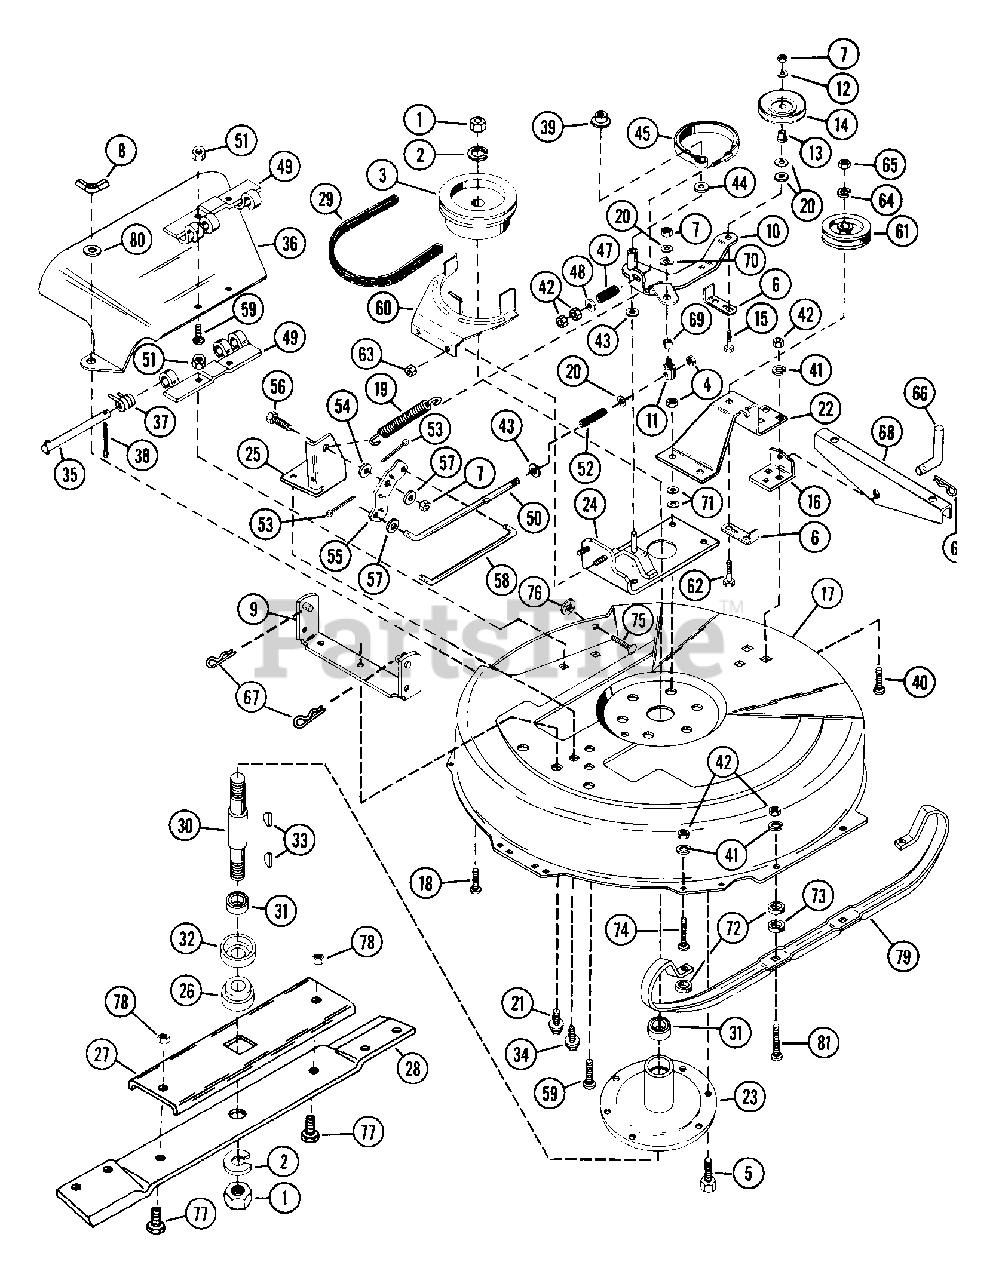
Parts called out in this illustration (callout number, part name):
1	NUT-JAM .75-10 PL
2	WSHR-LK .750X.188 MED PL
3	MOWER SHEAVE
4	NUT-LK-CTR .375-16 GR A PL
5	BLT-HEX .38-16X1.00 PL
6	BELT FINGER
7	NUT-LK .312-18 GR A PL
8	NUT-WING W/INSERT .312 - 18
9	FRONT MOUNTING BRACKET
10	IDLER ARM
11	ROD PIVOT
12	WSHR-FL-STL .323X.625X.062 PL
13	SPCR, BRG .315X.50X.688X.281
14	IDLER
15	BLT-HEX .31-18X1.50 PL GR2
16	REAR MOUNTING BRACKET
17	32 IN MOWER PAN SERVICE ASSEMB
18	BLT-RDHDSQNK .31-18X1.00 PL
19	SG-TENS .072X.51X5.31 WLD 25
20	WSHR-FL-STL .38X.875X.083 PL
21	BLT-SCRHFWH .38-16X.50 PL
22	IDLER MOUNT
23	SPINDLE HOUSING
24	PIVOT PLATE
25	DECK PIVOT BRACKET
26	RETAINER HUB
27	BLADE TRAY
28	MOWER BLADE 32
30	SPINDLE SHAFT
31	BRG-BALL .750X1.781X.61
32	BEARING SLINGER
33	KEY-WDRF .188X.75X.313 SAE 9
34	BLT-SERHFWH .31-18X.50 PL
35	CLEVIS PIN
36	CHUTE DEFLECTOR
37	SG-TORS .090X.37X.63
38	PIN-COTR .09X.75 PL
39	FASTENER
40	BLT-RDHDSQNK .31-18X.75 GR5 PL
41	WSHR-LK .312X.097 PL HVY
42	NUT-HEX .312-18
44	WSHR-FL-STL .531X1.062X.095 PL
45	BRAKE BAND
46	PIN-COTR .06X.50
47	SG-COMP .072X.687X.75
48	WSHR-FL-STL.344X.688X.065PL
49	HINGE PLATE
50	CLUTCH ROD
51	NUT-LK-CTR .250-20 PL
52	SG-COMP .148X.68X6.5 WLD 90
53	PIN-COTR .12X.75 PL
54	SPACER BUSHING .5 X .32 X .163
56	BLT-HEX .31-18X.88 PL GR2
57	WSHR-FL-STL .344X1.125X.063PL
58	CLUTCH ROD
59	BLT-RDHDSQNK .25-20X.62 PL
60	BELT FINGER
61	IDLER-V 3.06 X .38
62	BLT-HEX .38-16X1.75 PL GR2
63	NUT-FLG. .312-18 PL
64	WSHR-LK .375X.094 MED PL
65	NUT-HEX .375-16
66	CLEVIS PIN
67	PIN-HAIR INT .08X.38X1.42 YWZC
68	SWIVEL BRACKET
69	SPACER BUSHING .5 X .32 X .21
70	WAVE WASHER .531X.781X.125FH
71	WSHR-FL-STL .438X1.0X.083 PL
72	SPACER .328X.750X.375
73	SPACER BUSHING .5 X .32 X .21
74	BLT-RDHDSQNK .31-18X1.75 SHTPL
75	BLT-RDHDSQNK .312-18X.62SHTPL
76	NUT-PUSH .312
77	BLT-HEX .38-16X1.00 PL GR5
78	NUT-LK TOP .375-16 GR C YWZC
79	32 IN ADJUSTABLE SKID
80	WSHR-FL-STL .328X.875X.062 PL
81	BLT-RDHDSQNK .31-18X1.25 SHTPL
